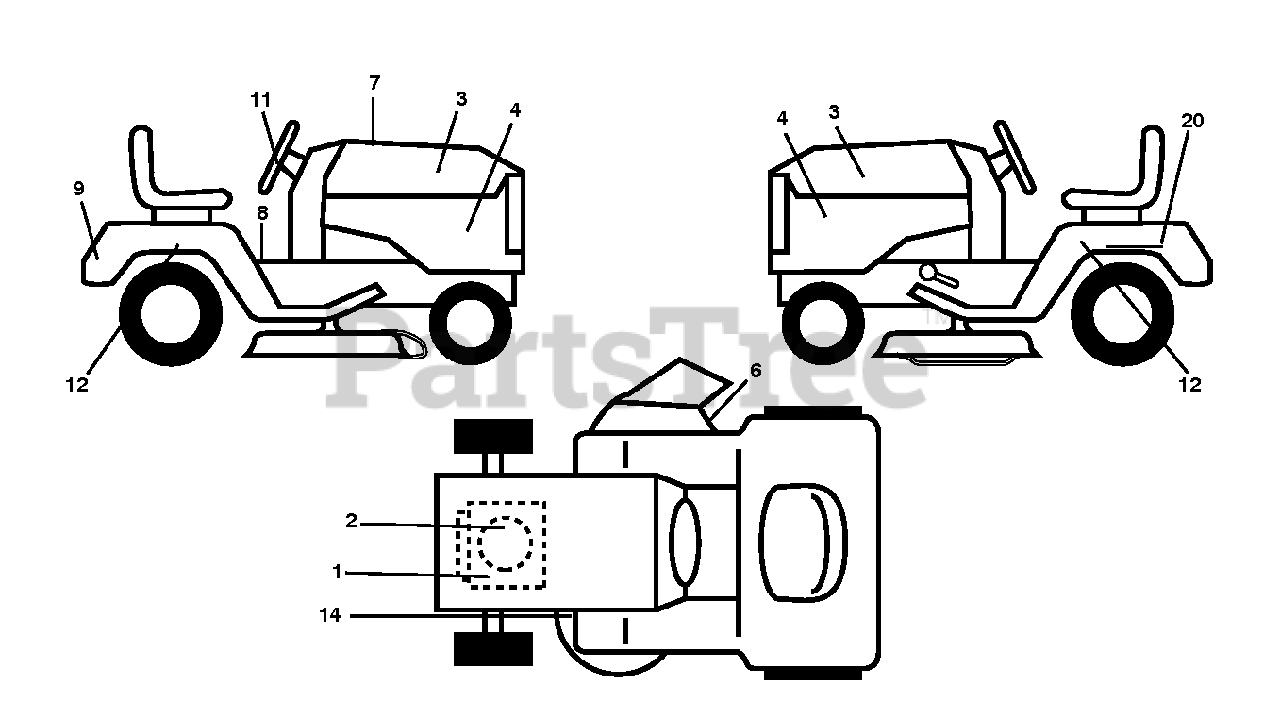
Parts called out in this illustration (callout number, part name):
2	DECAL.ENGINE.B&S.(278443)
3	DECAL.HOOD.POULAN.PRO.SET
6	DECAL.WARN.KEEP.HAND.AWAY
8	Fender Engine Warning Decal
9	DECAL.REAR.FNDR.LOGO.POULAN.PR
11	DECAL.STEER.WHEEL.POULAN.PRO
14	DECAL V BELT SCHEMATIC
20	DECAL BTRY SYMBOLS
